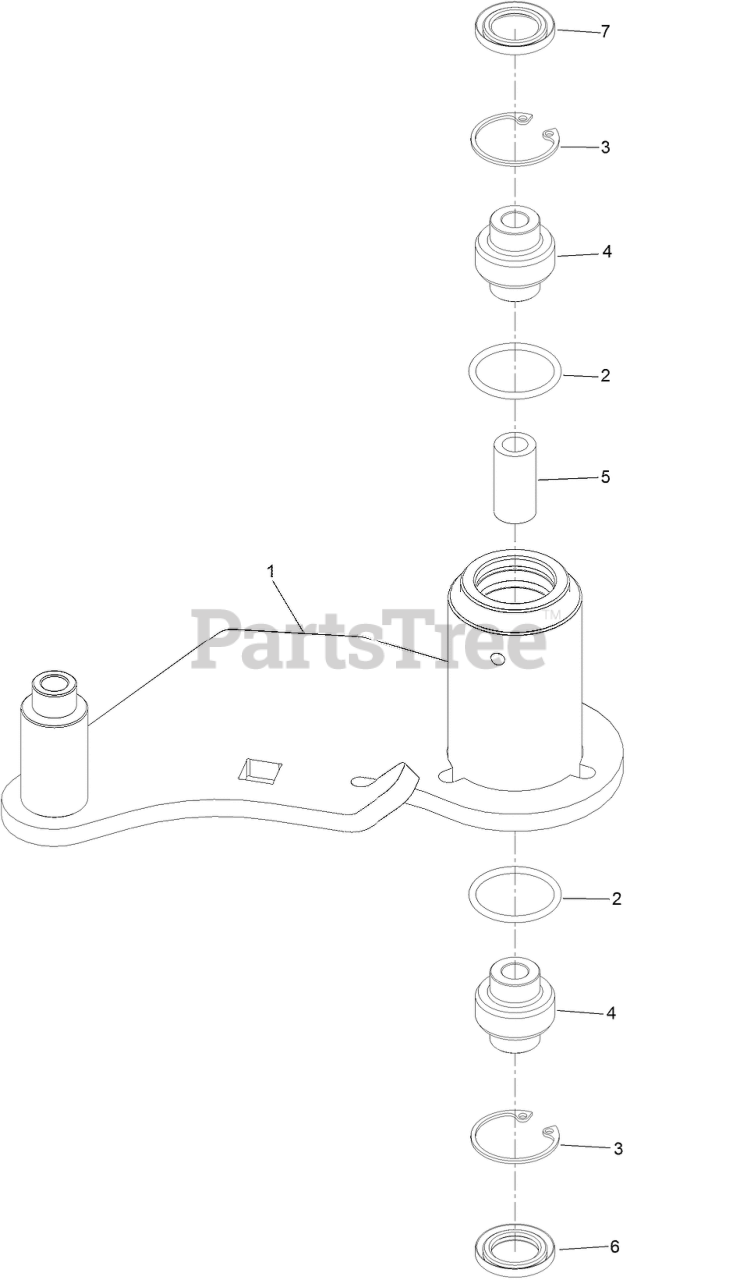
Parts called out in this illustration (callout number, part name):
1	Idler-Deck
3	RING-SNAP
4	BEARING-SPHERICAL
6	SEAL-LIP, DOUBLE
7	SEAL-LIP, SINGLE
